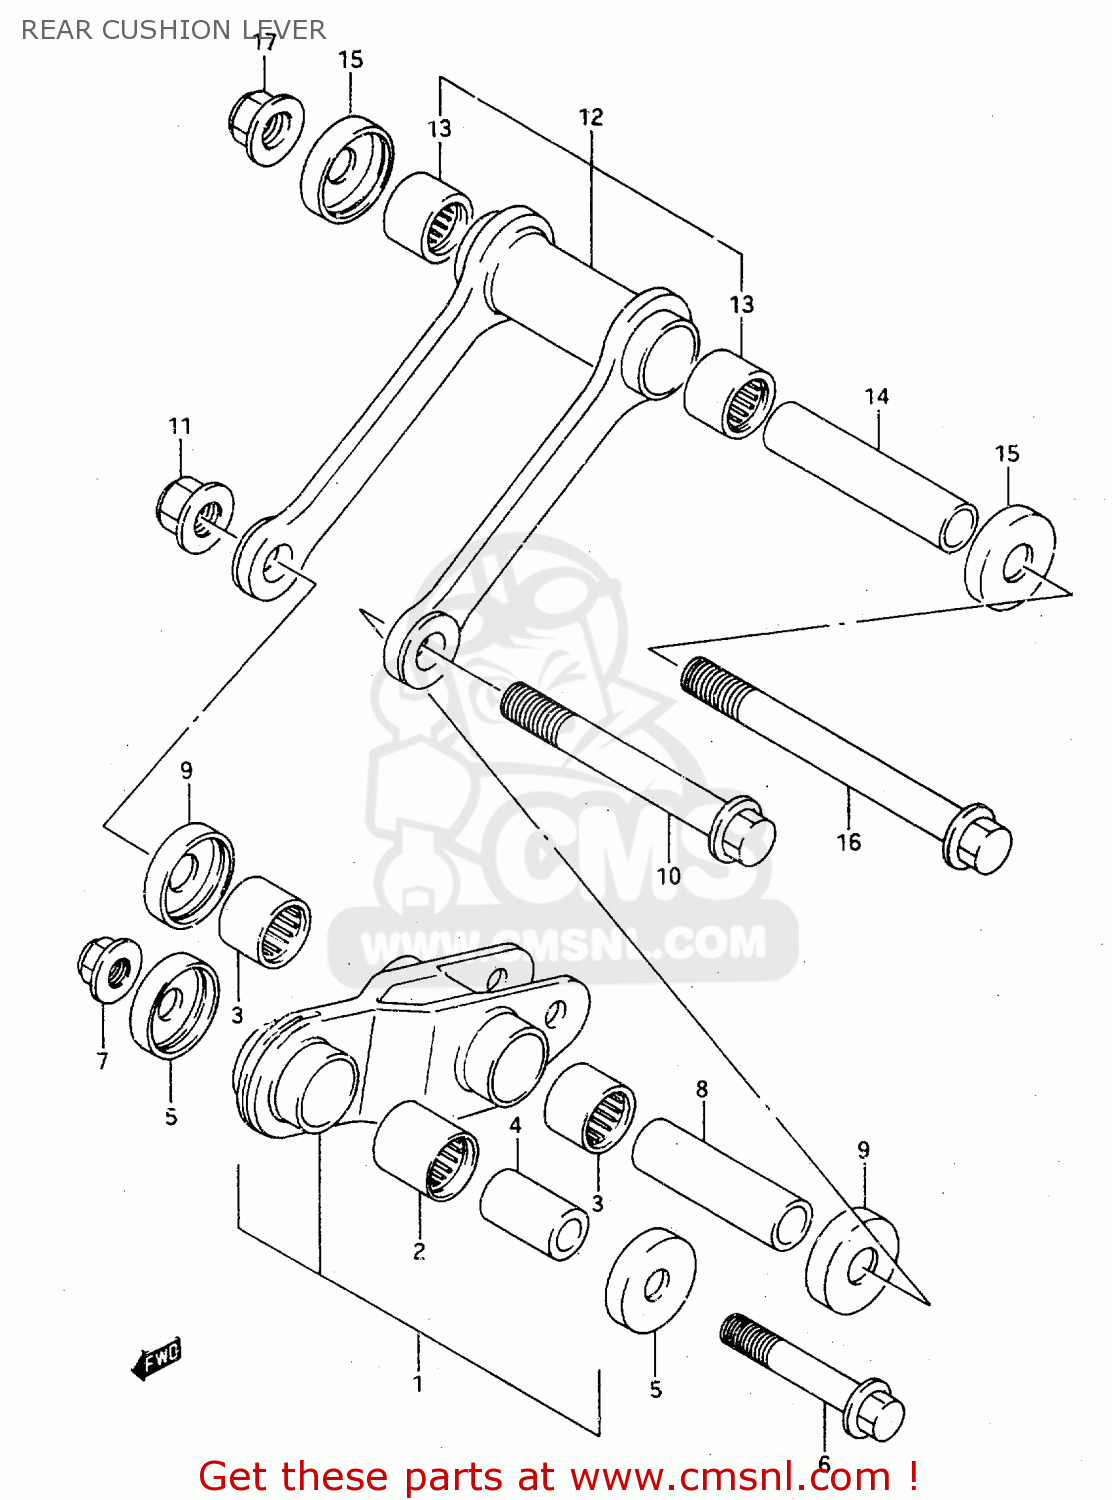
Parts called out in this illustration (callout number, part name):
1	LEVER SET, REAR CUSHION
2	BEARING(20X27X32)
3	BEARING(20X27X23.5)
4	SPACER,REAR CUSHION LEVER
5	SEAL,RR CUSHION LEVER FR DUST
6	BOLT,RR CUSHION LEVER FR
7	NUT 12MM
8	SPACER (14X20X70)
9	SEAL,RR CUSHION LEVER CTR DUST
10	BOLT(14X106)
11	NUT
12	ROD SET,RR CUSHION LEVER
13	BEARING(20X27X23.5)
14	SPACER(14X20X102)
15	SEAL,RR CUSHION LEVER CTR DUST
16	BOLT(14X144)
17	NUT
